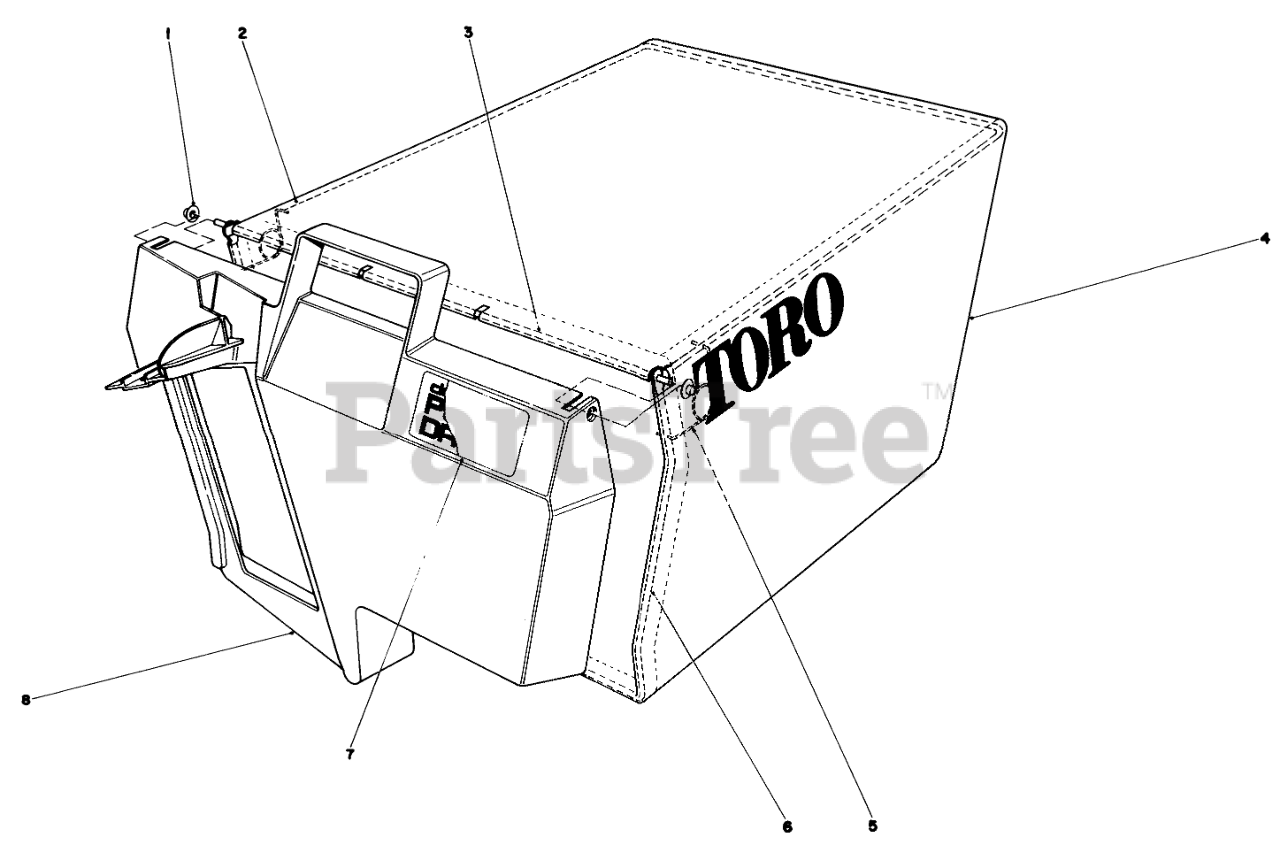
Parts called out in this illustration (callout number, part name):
1	NUT-PUSH
2	FRAME-BAG, UPPER
3	HINGE-DOOR, BAG
4	Bag
5	SPRING
6	FRAME-BAG
7	BAG DOOR DECAL
8	Door Grass Bag
